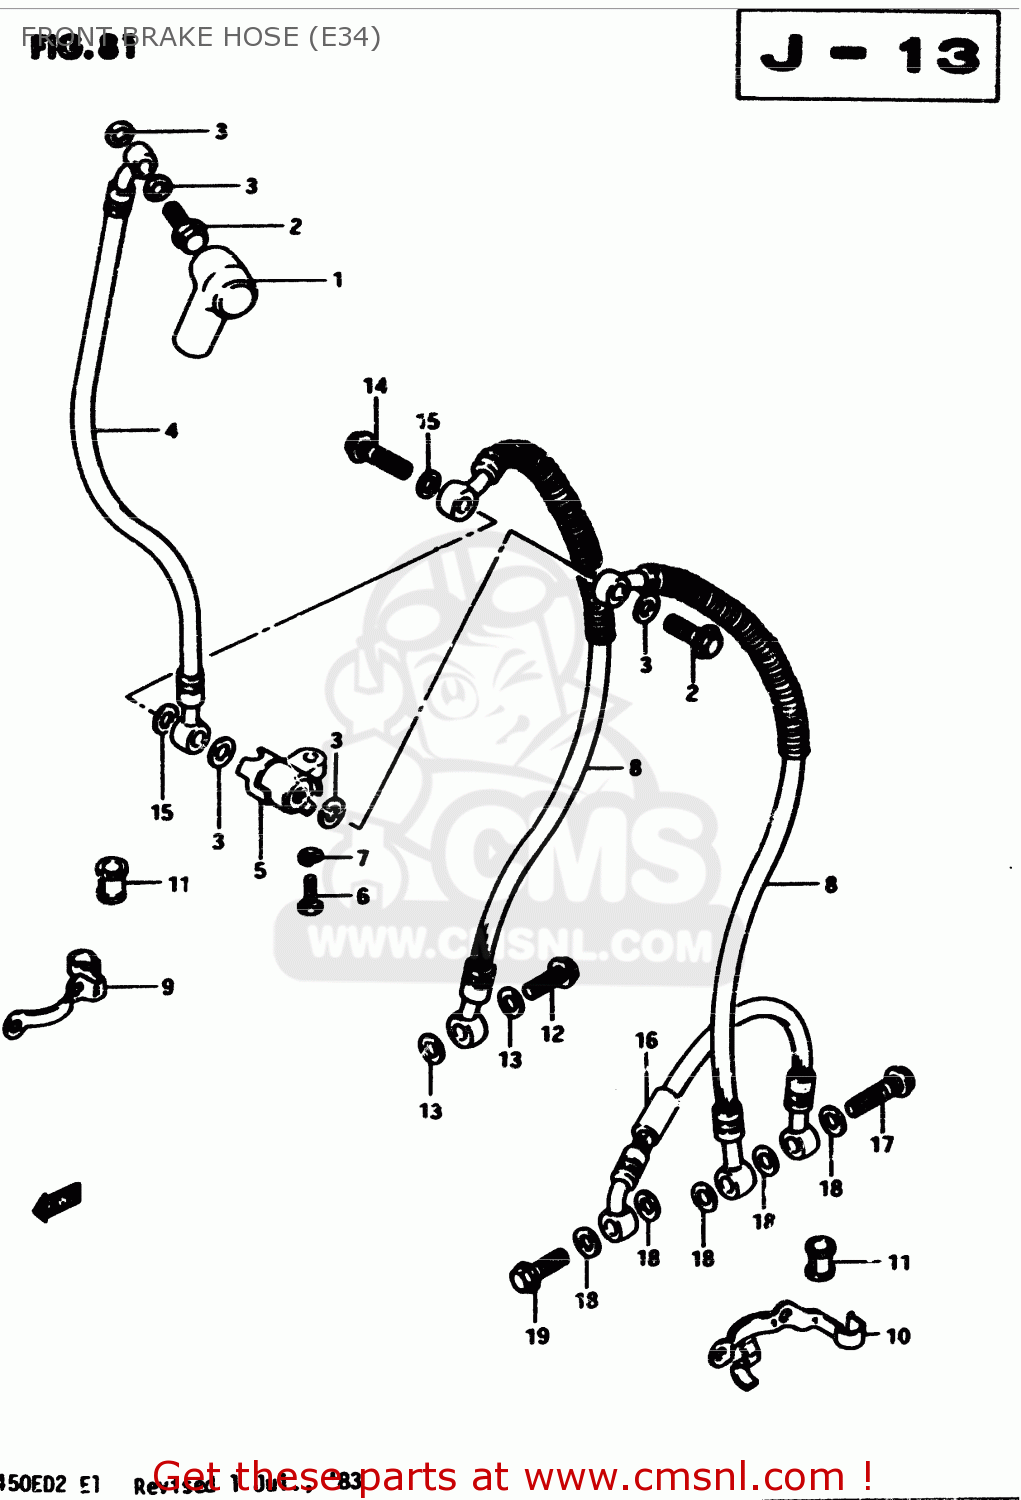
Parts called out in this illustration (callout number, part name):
1	BOOT,MASTER CYLINDER
2	BOLT,UNION
3	WASHER
4	HOSE,FRONT BRAKE
5	JOINT,BRAKE HOSE
6	BOLT
7	LOCK WASHER
8	HOSE, BRAKE NO.2
9	CLAMP, HOSE RH
10	CLAMP,BRAKE HOSE,LEFT
11	BUSH,BRAKE HOSE GUIDE,NO.2
12	BOLT,UNION
13	WASHER
14	BOLT,UNION
15	WASHER
16	HOSE, ANTINOSE DIVE
17	BOLT,UNION
18	WASHER
19	BOLT UNION
